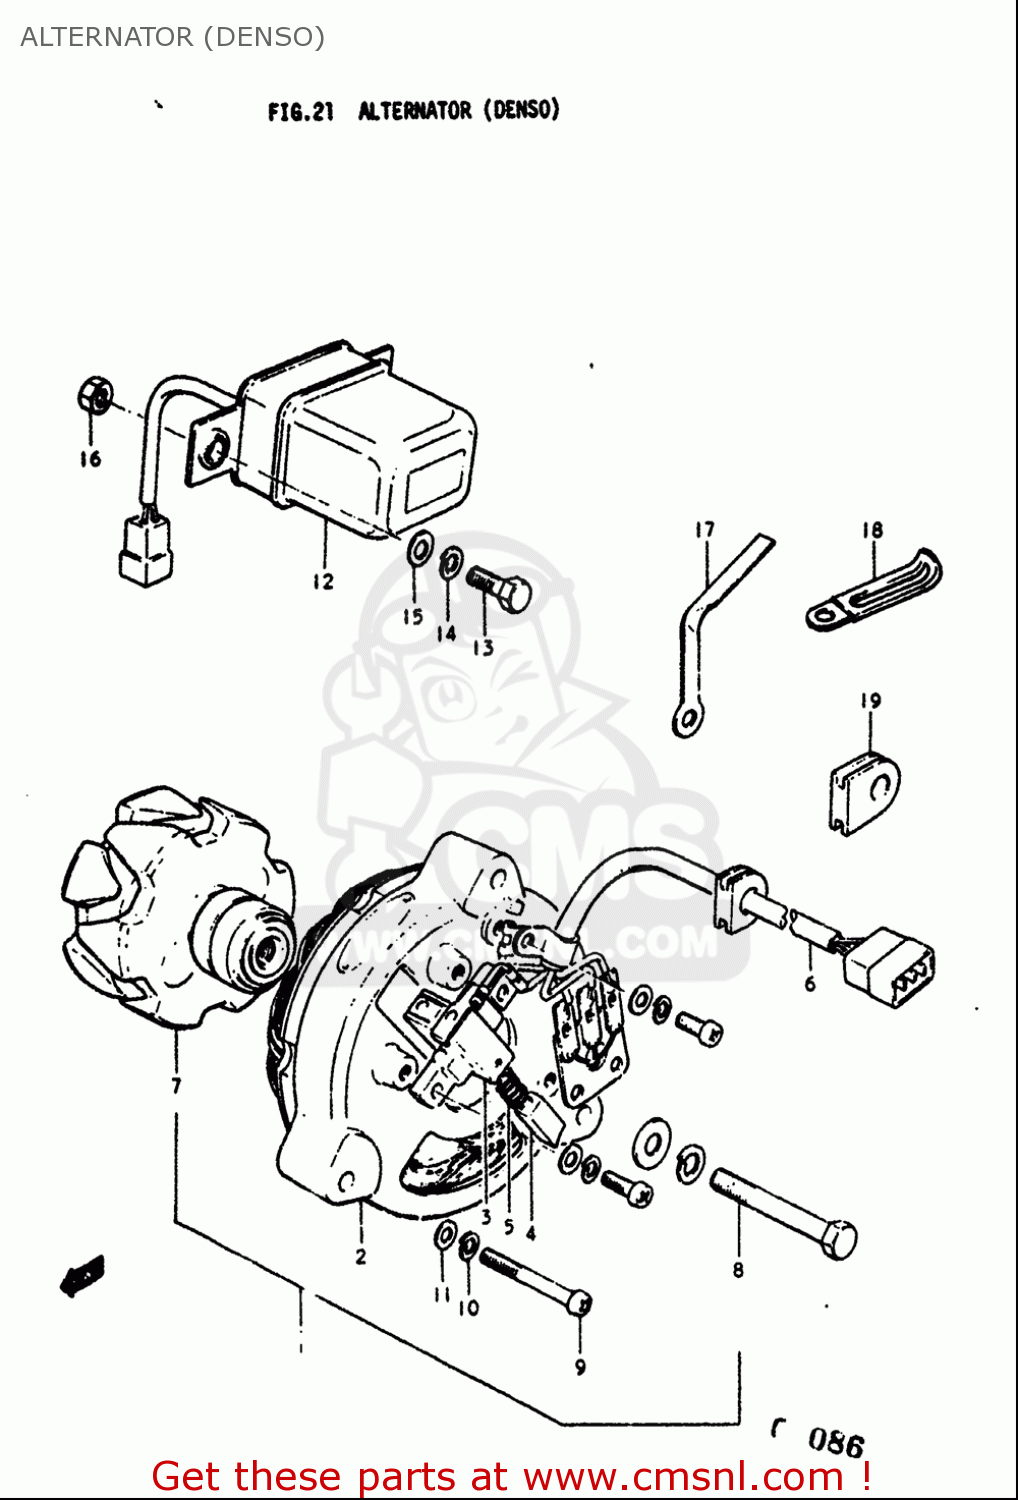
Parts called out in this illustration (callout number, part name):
3	HOLDER,CARBON BRUSH
4	BRUSH
5	SPRING
8	BOLT
9	SCREW
10	WASHER,LOCK
11	WASHER
12	REGULATOR ASSY,VOLTAGE
13	BOLT
14	WASHER,LOCK
15	WASHER
16	NUT
18	CLAMP
19	GROMMET
